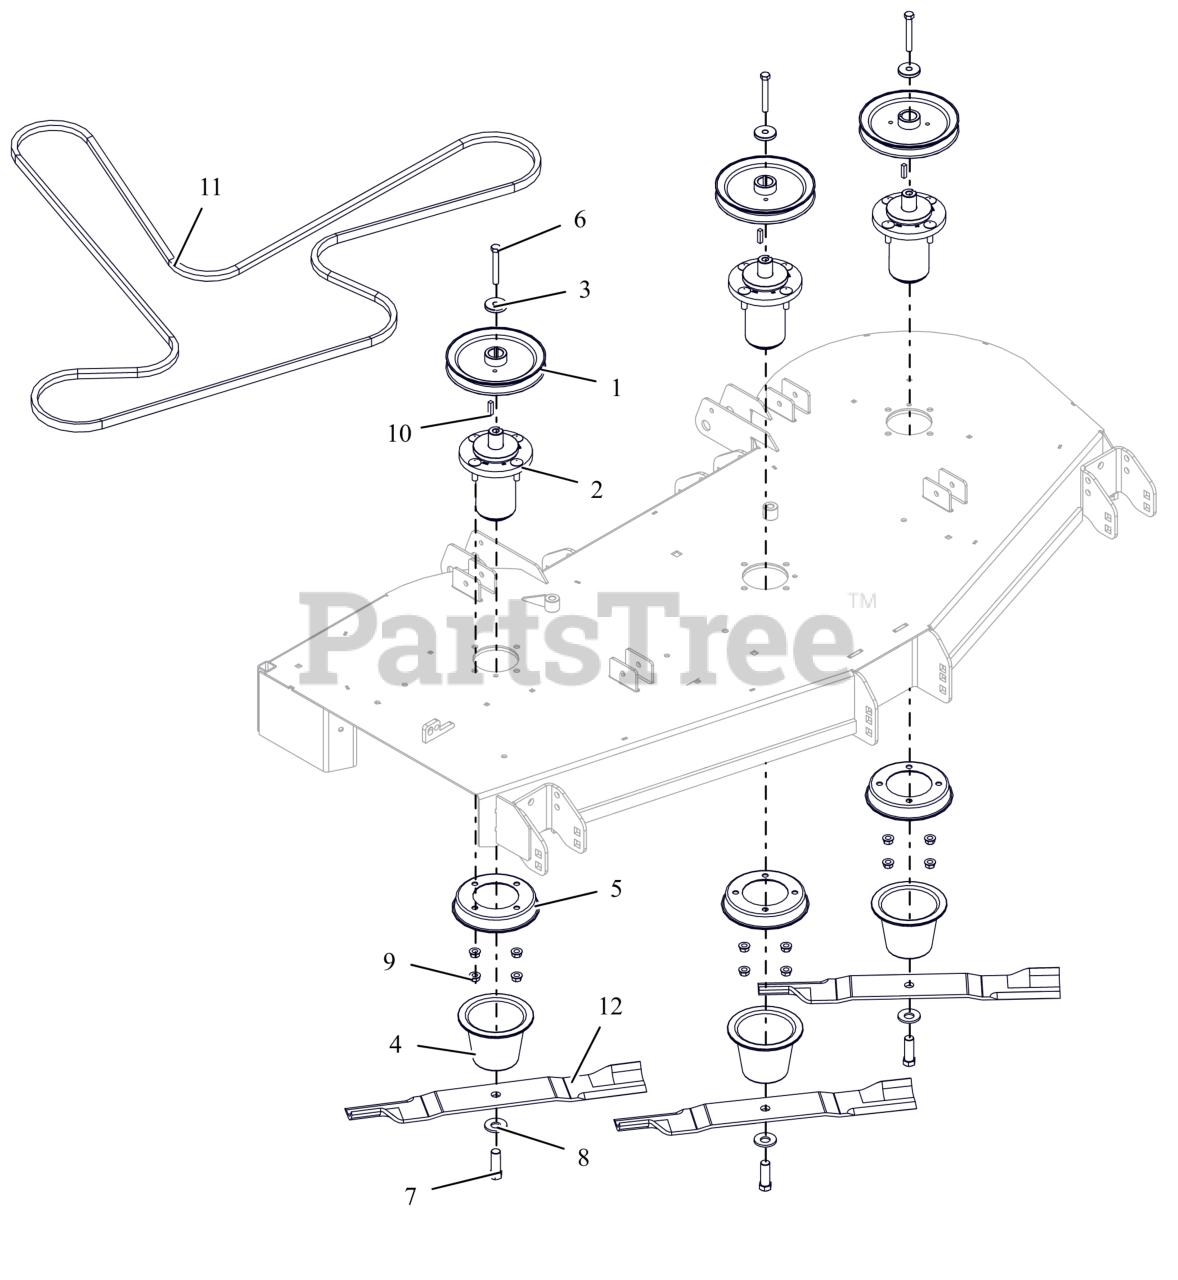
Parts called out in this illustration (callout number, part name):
1	PULLEY, V-1.00 ID X 6.75 OD
2	ASM, MAINT FREE ALUM SPINDLE
3	RETAINER, SHEAVE
4	GUARD, SPINDLE LOWER
5	GUARD, SPINDLE TOP
6	BLT, HEX .38-16X2.75 G8 ZCC
7	BLT, HEX .62-18X1.75 G8 ZCC
8	WSHR-BLVL .669X1.535X.138
9	NUT-LK-CTR-FLG .375-16 GF ZCC
10	KEY, SQ .25X.25X1.00 RC 40-50
11	BELT, V, RAW EDGE EPDM
12	BLADE, MOWER (20.50")
